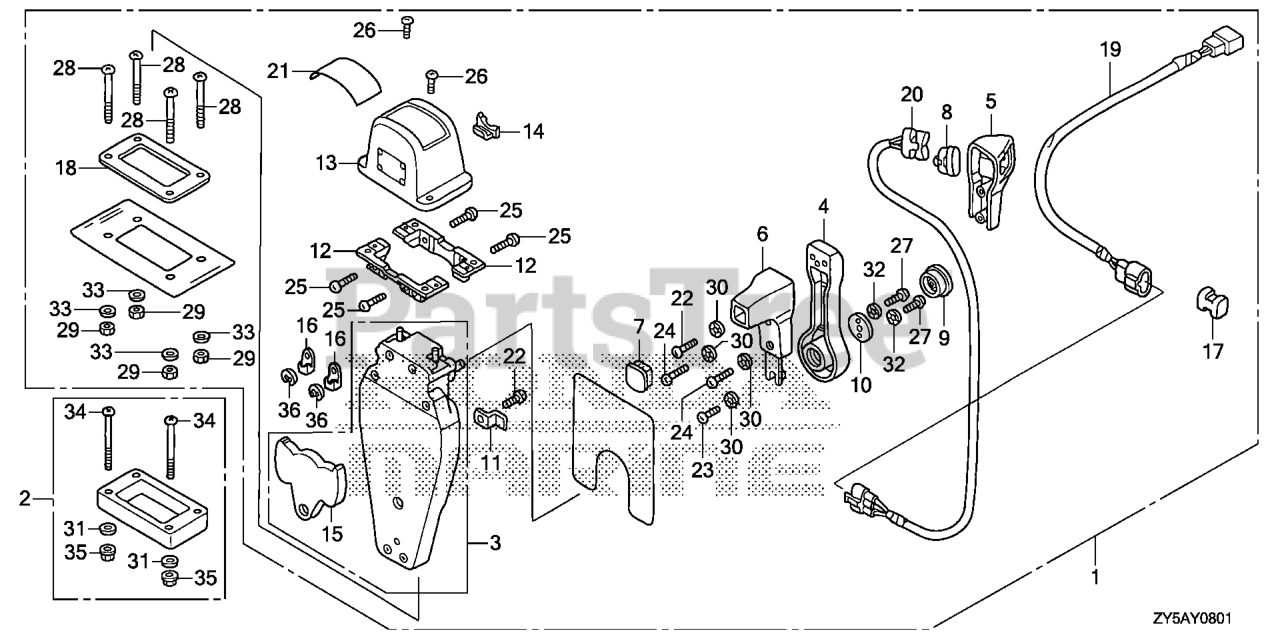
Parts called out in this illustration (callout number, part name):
1	BOX KIT, REMOTE CONTROL (TOP MOUNT SINGLE)(L)
2	SPACER KIT, REMOTE CONTROL BOX (TOP MOUNT SINGLE)
3	HOUSING ASSY., R. (INNER) (TOP MOUNT)
4	HANDLE, REMOTE CONTROL
5	COVER, R. GRIP
6	GRIP, REMOTE CONTROL HANDLE
7	CAP, GRIP
8	CAP, SWITCH
9	BUTTON, THROTTLE
10	PLATE, HANDLE
11	PLATE, CABLE CLAMP
12	BRACKET, REMOTE CONTROL HOUSING
13	HOUSING, REMOTE CONTROL BOX
14	HOUSING, LEAD
15	PLATE, DWELL
16	TERMINAL, CABLE
17	SPACER, CABLE CLAMP
18	GASKET, SINGLE
19	SUB-HARNESS ASSY., POWER TRIM-TILT (B)
20	SWITCH ASSY., POWER TRIM-TILT
21	MARK, REMOTE CONTROL (SINGLE)
22	SCREW, PAN (5X16)
23	SCREW, PAN (5X10)
24	SCREW, PAN (5X20)
25	SCREW, PAN (5X18)
26	SCREW, PAN (4X10)
27	SCREW, PAN (6X18)
28	SCREW, PAN (5X40)
29	NUT, HEX. (5MM)
30	WASHER, LOCK (5MM)
31	WASHER, PLAIN (5MM)
32	WASHER, LOCK (6MM)
33	WASHER, PLAIN (5MM)
34	SCREW, PAN (5X65)
35	NUT, HEX. (5MM)
36	E-RING (6MM)
